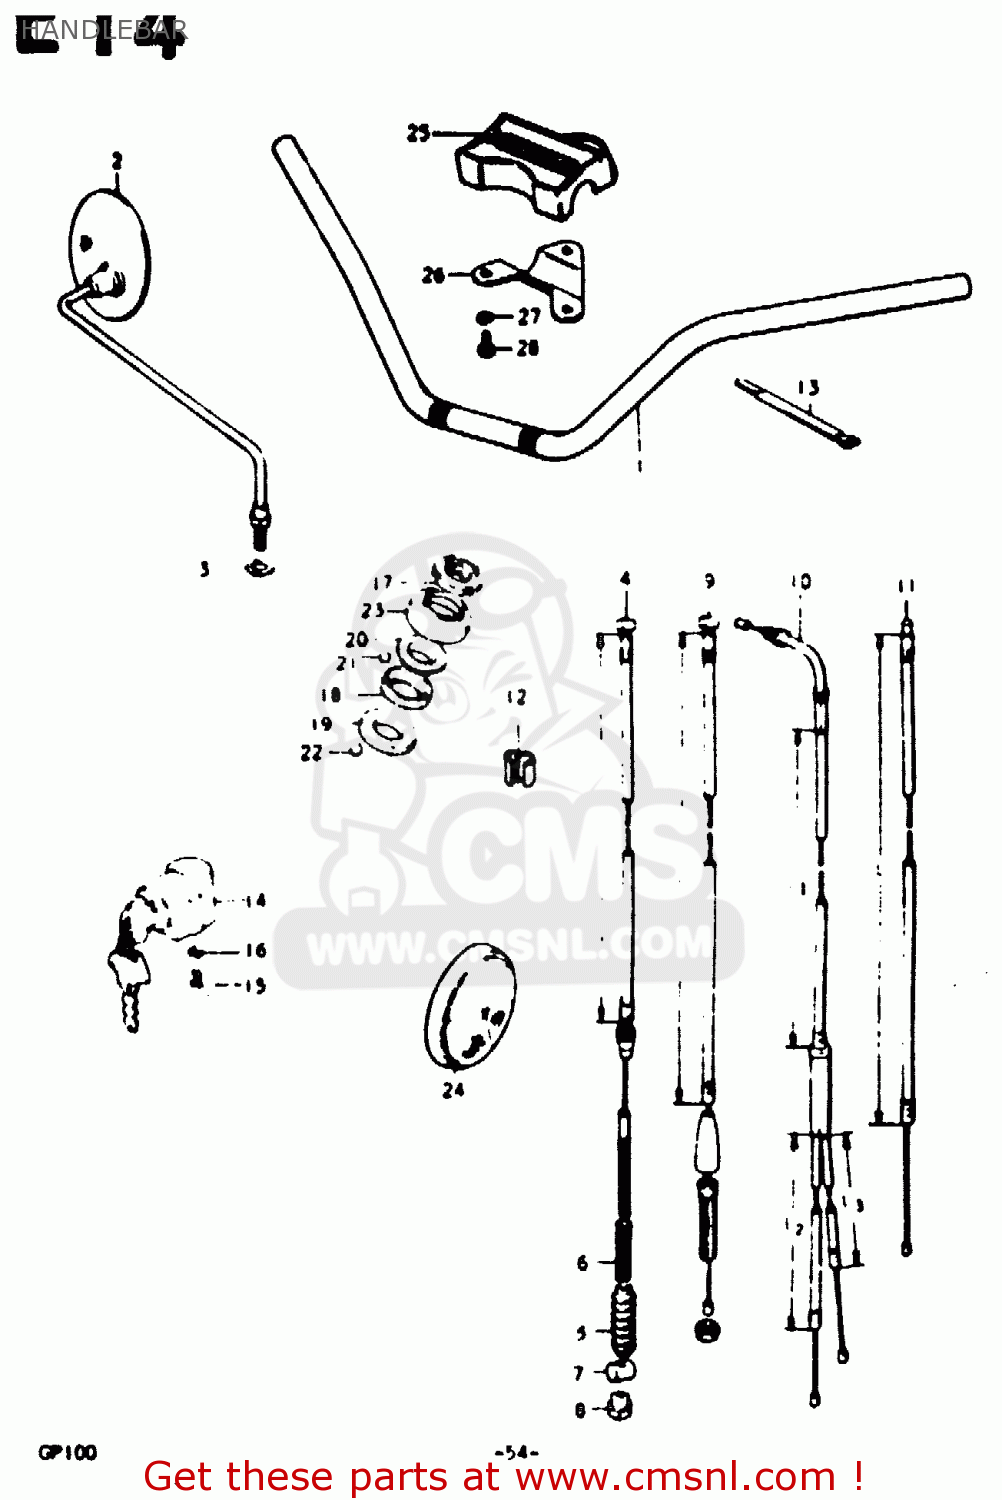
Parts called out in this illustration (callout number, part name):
1	HANDLEBAR (TO 56110-39101)
2	MIRROR ASSY, REAR VIEW
3	WASHER
9	CABLE ASSY, CLUTCH (L:900)
10	CABLE ASSY, THROTTLE (L1:545, L2:320, L3
11	CABLE STARTER
12	CLIP
13	CLAMP
14	LOCK ASSEMBLY,STEERING
15	SCREW
16	LOCK WASHER
17	NUT,STEERING STEM(25X44X10)
18	RACE,STEERING INNER UPR
19	LACE,STEERING INNER LWR
20	RACE,STEERING OUTER UPR
21	BALL
22	BALL
23	DUST SEAL,STEERING UPR
24	REFLEX REFLECTOR, FRONT (TO 35950-35011)
